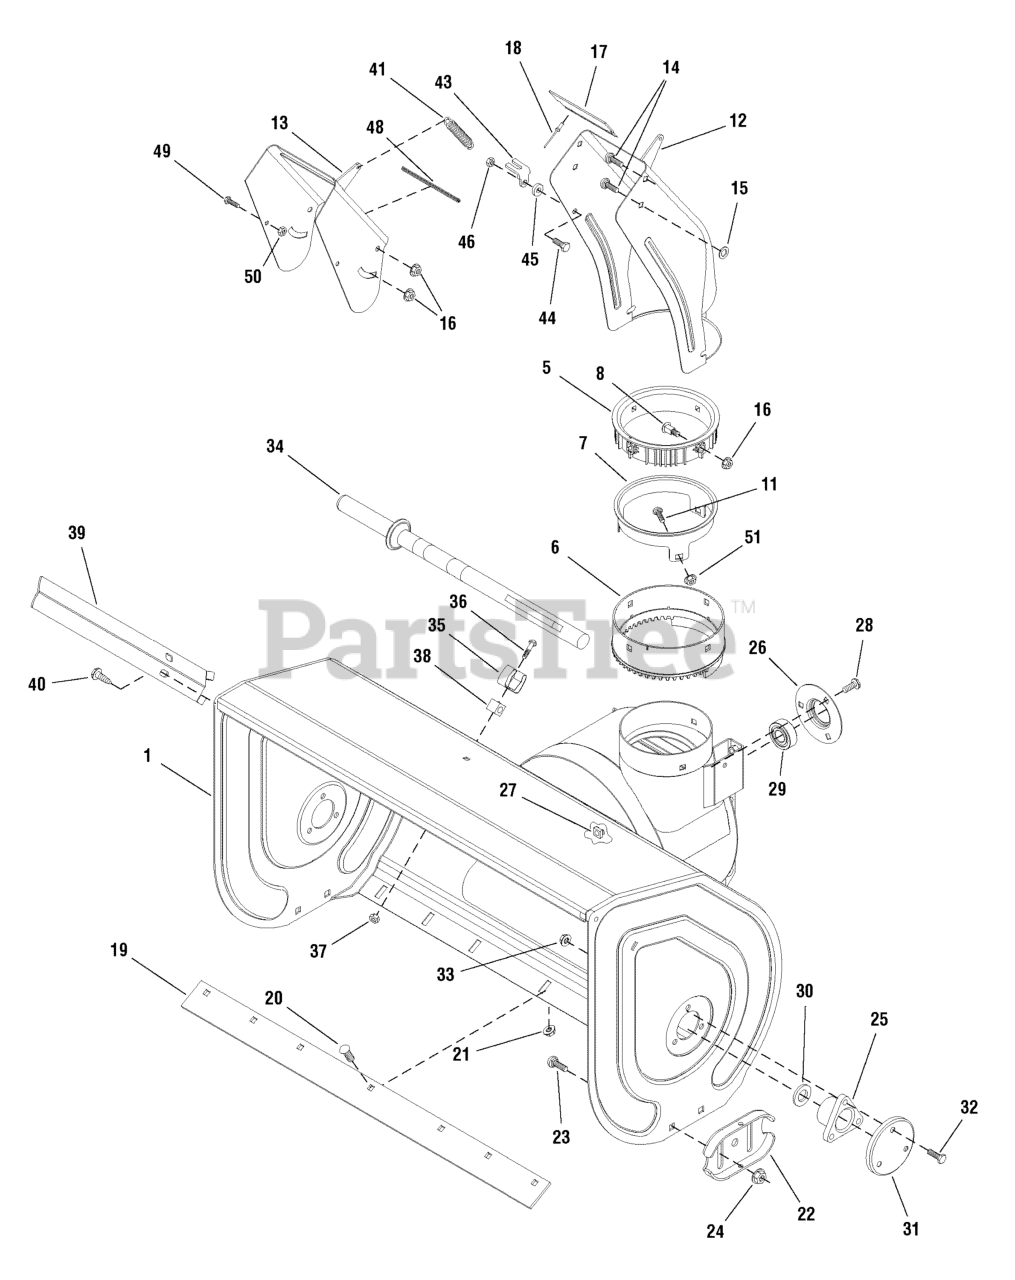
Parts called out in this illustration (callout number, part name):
1	HOUSING ASSEMBLY, 28"
1	HOUSING ASSEMBLY, 30"
1	HOUSING ASSEMBLY, 32"
5	RING, Retainer, Inner
6	RING, Outer Chute
7	ADAPTER, Chute Ring
8	CARRIAGE BOLT, 5/16 - 18 x 1
11	CARRIAGE BOLT, 5/16 - 18 x 5/8, G5
12	CHUTE & BRACKET ASSEMBLY, Lower
13	CHUTE ASSEMBLY
14	CARRIAGE BOLT, 5/16 - 18 x 3/4, G5
16	NUT, Hex Flange ESNA, 5/16 - 18
17	FLAP, Chute Insert
18	RIVET, Pop
19	BLADE, Scraper, 28"
19	BLADE, Scraper, 30"
19	BLADE, Scraper, 32"
20	CARRIAGE BOLT, 5/16 - 18 x 5/8, G5
21	NUT, Hex Flange Two-Way Lock, 5/16 - 18
22	SKID, Shoe Reversible
23	CARRIAGE BOLT, 3/8 - 16 x 3/4, G5
24	NUT, Hex Flange ESNA, 3/8 - 16
25	BEARING, Flange
26	BEARING, Retainer
27	RETAINER, Nut, 5/16 - 18
28	SCREW, Hex Whiz Lock Flange, 5/16-18 x 3/4
29	BEARING, Greased
31	CAP, Bearing
32	CAPSCREW, Hex Head, 5/16 - 18 x 7/8, G5
33	NUT, Hex Flange Whiz Lock, 5/16 - 18
34	STICK, Cleanout w/Brush
35	CLIP, Retainer
36	SCREW, Hex Washer Head Slot
37	NUT, Hex Lock with Nylon Insert, 10 - 24
38	BLOCK, Universal Pivot
39	CUTTER, Drift
40	SCREW, Hex Washer Head Taptite, 5/16-18 x 3/4
41	SPRING, Extension
43	BRACKET, Remote Chute
44	CAPSCREW, Hex Head, 5/16 - 18 x 3/4, G5
46	NUT, Hex Centerlock, 5/16 - 18
48	EDGING, with Adhesive
49	BOLT, Shroud 1/4 x 5/16 - 1/4
50	NUT, Hex Flange Centerlock, 1/4 - 20
51	NUT, Hex Keps Conical Washer, 5/16-18
